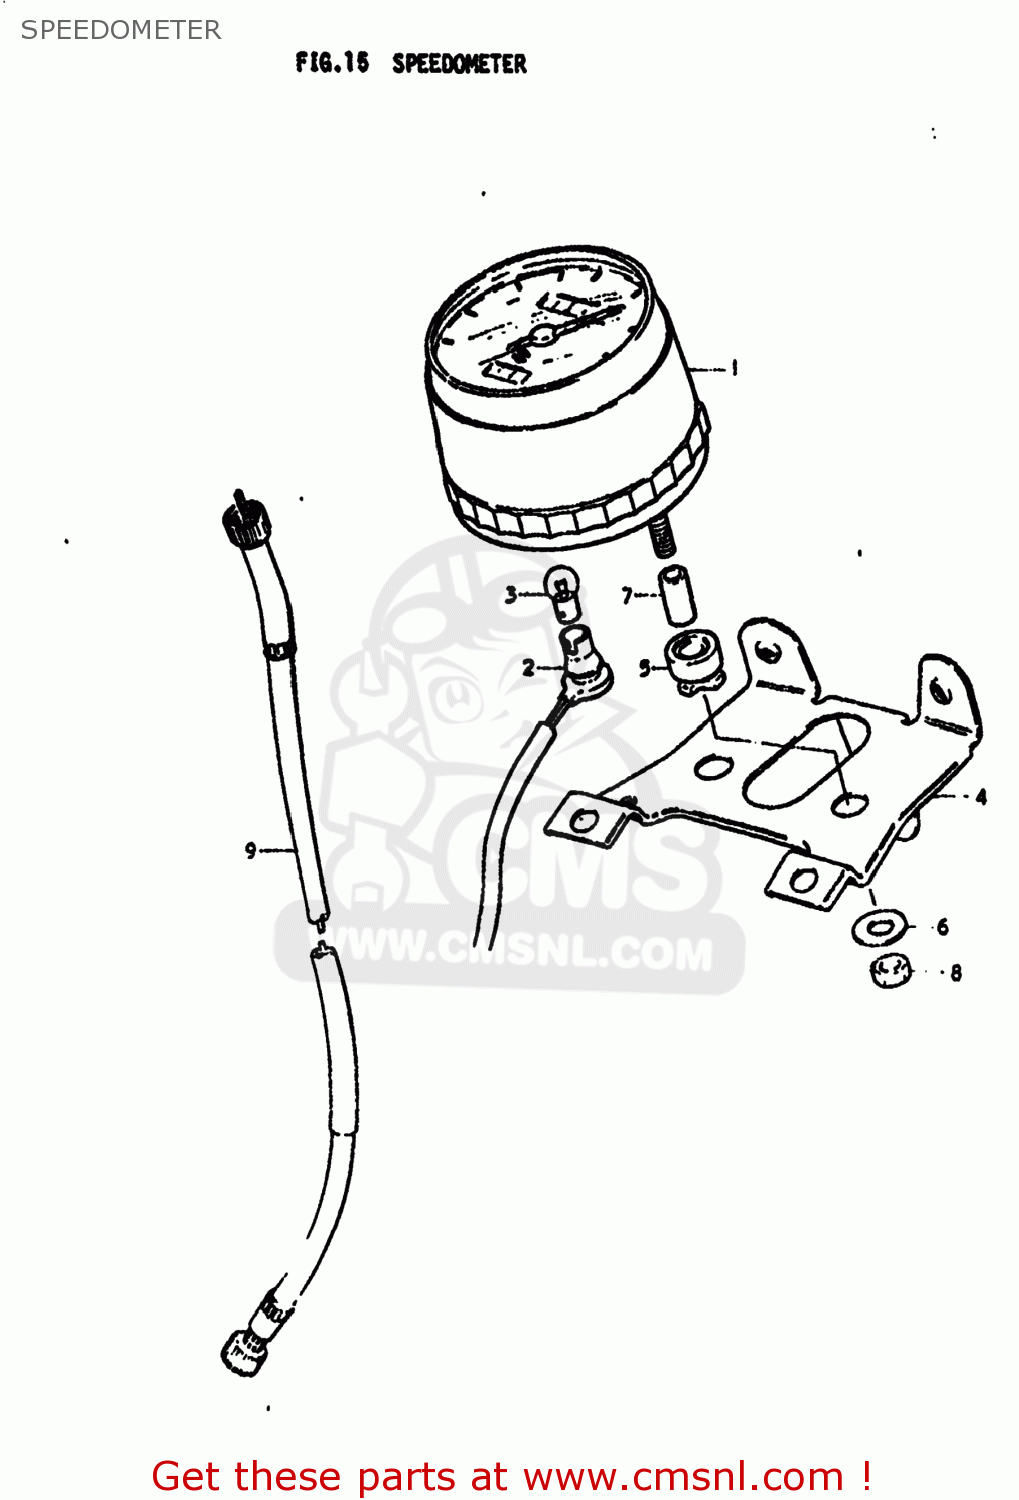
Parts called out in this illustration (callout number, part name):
0	SPEEDOMETER ASSEMBLY
1	SPEEDOMETER ASSEMBLY
2	SOCKET,METER
3	BULB(6V1.7W,STANLEY,A61A)
4	BRACKET,METER
5	CUSHION,METER NO.1
6	WASHER
7	SPACER,METER
8	NUT
9	CABLE ASSEMBLY,SPEEDOMETER
